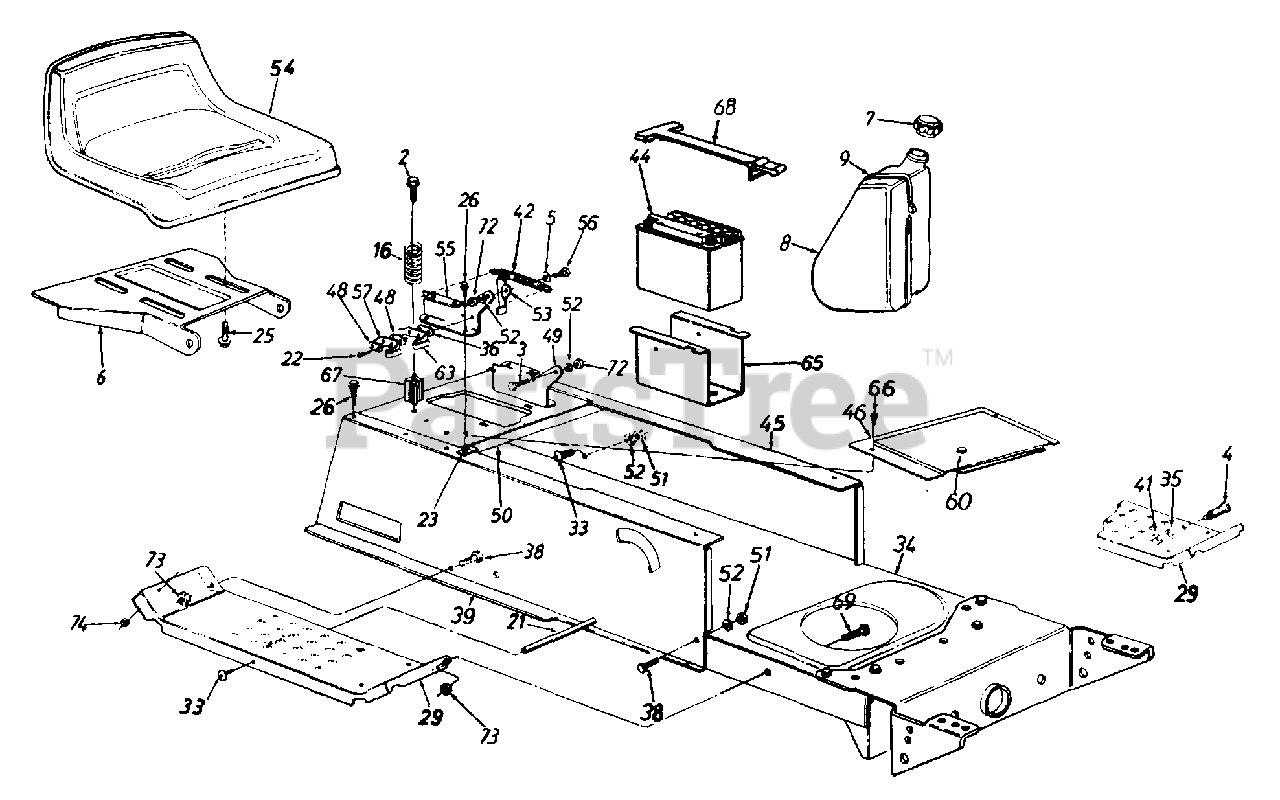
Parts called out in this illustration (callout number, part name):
2	Hex Wash. Hd. Tap Scr. 5/16-18 x 3.25" Lg.
3	Shld. Bolt .437" Dia. x .162"
4	Shld. Bolt .50" Dia. x .84"
5	Spr-Wash. .445" I.D. x .75
7	Fuel Cap
9	Tie Strap
13	Hex Nut 1/4-20 Thd.
16	Compression Spring
21	Running Board Rod
22	Hex Wash. Hd. AB-Tap Scr. #8 x .50" Lg.
23	Speed Nut #10Z
25	Hex Tap Scr. 3/8-16 x .62" Lg.
26	Hex Wash. Hd. AB-Tap Scr. 5/16 x .75" Lg.
35	L-Wash. 3/8" I.D.
36	Insulator Boss Plate
38	Hex Bolt 5/16-18 x .75" Lg.
39	Upper Frame - R.H.
41	Hex Nut 3/8-16 Thd.
42	Extension Spring 5.31" Lg.
44	12-V Battery
45	Upper Frame - L.H.
52	L-Wash. 5/16" I.D.
53	Seat Lift Brkt.
54	Seat
56	Shld. Bolt .437" Dia. x .268"
57	Spring Switch (Seat)
60	Snap Bushing
63	Safety Switch (Seat)
66	Truss Mach. B-Tap Scr. #10 x .5" Lg.
67	Spring Spacer
68	Battery Retainer Strap
69	Hex Bolt 5/16-18 x .75" Lg.
72	Hex Nut 5/16-18
73	Hex Sems Nut 5/16-18 Thd.
74	Hex Sems Nut 1/4-20 Thd.
